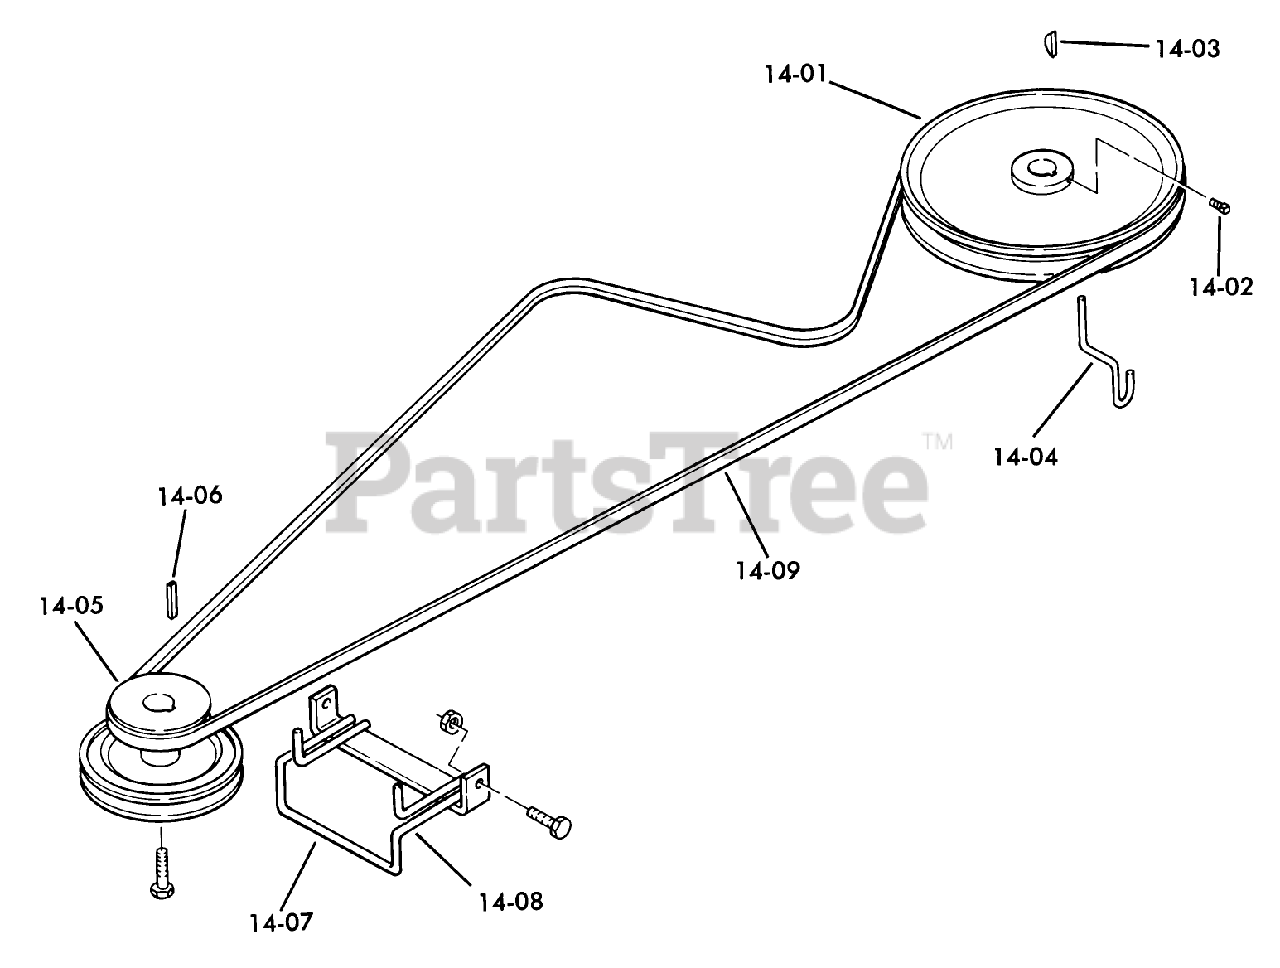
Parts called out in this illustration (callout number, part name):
14-01	Pulley-Transmission
14-02	Set Screw
14-03	KEY WOODRUFF
14-04	Belt Retainer
14-05	PULLEY-ENGINE
14-06	Key
14-07	HEX HD CAP SCREW
14-08	Belt Bracket
14-09	V-BELT, TRANSMISSION DR.
